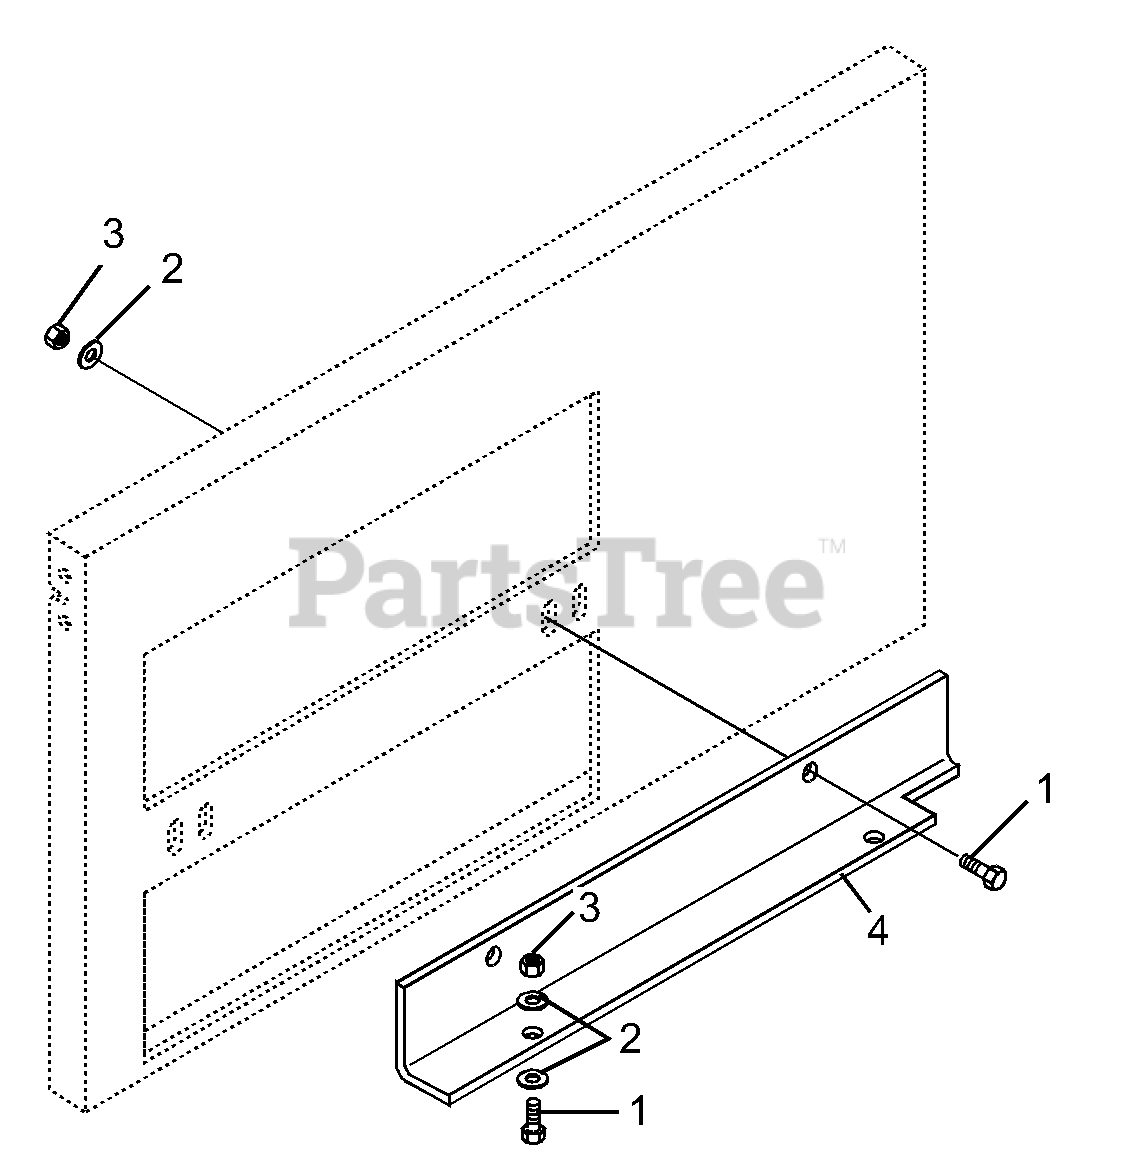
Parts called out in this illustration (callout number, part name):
1	Bolt-Hex .38-16 x 1.00 Grade 5
2	Washer-Flat-Steel .406 x .812 x .065
3	Nut-Locking-Nylon .375-16 Grade 2
4	Adapter-PRO 36
